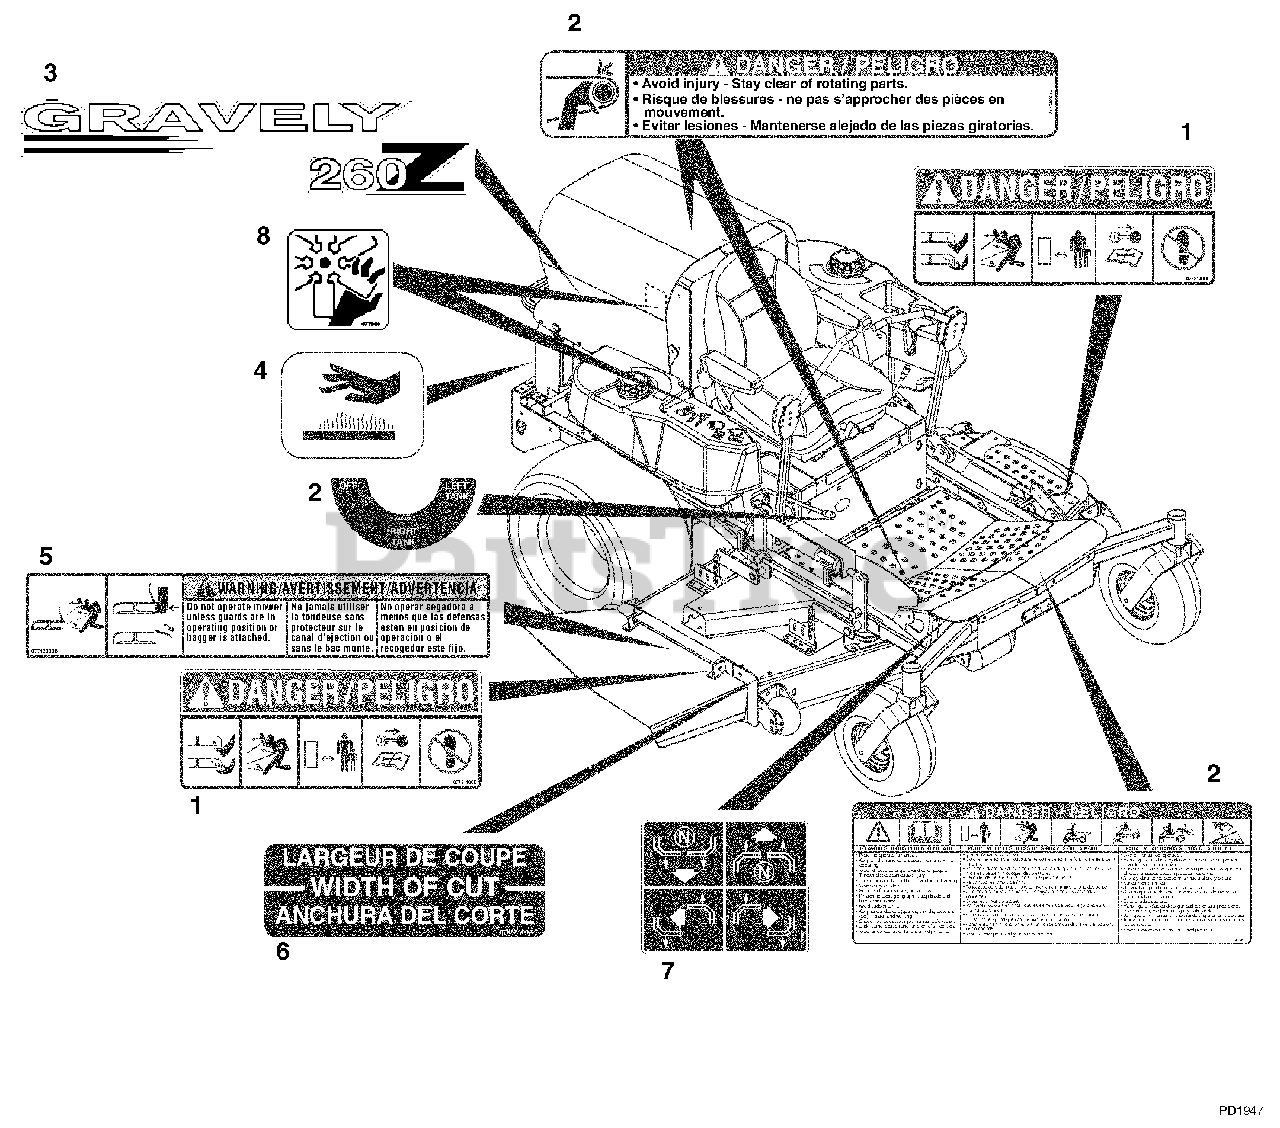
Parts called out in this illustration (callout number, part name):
1	Decal, Mower Pan Head Danger
2	Set, Decal-Common Danger/Fuel
3	Decal, PM-260Z Hood (036, 038, 309)
3	Decal, PM-272Z Hood (037, 039)
4	Decal-Hot Surface
5	Decal, Warning
6	Decal, Width of Cut
7	Decal-Instructional
8	Decal, Danger Fan
